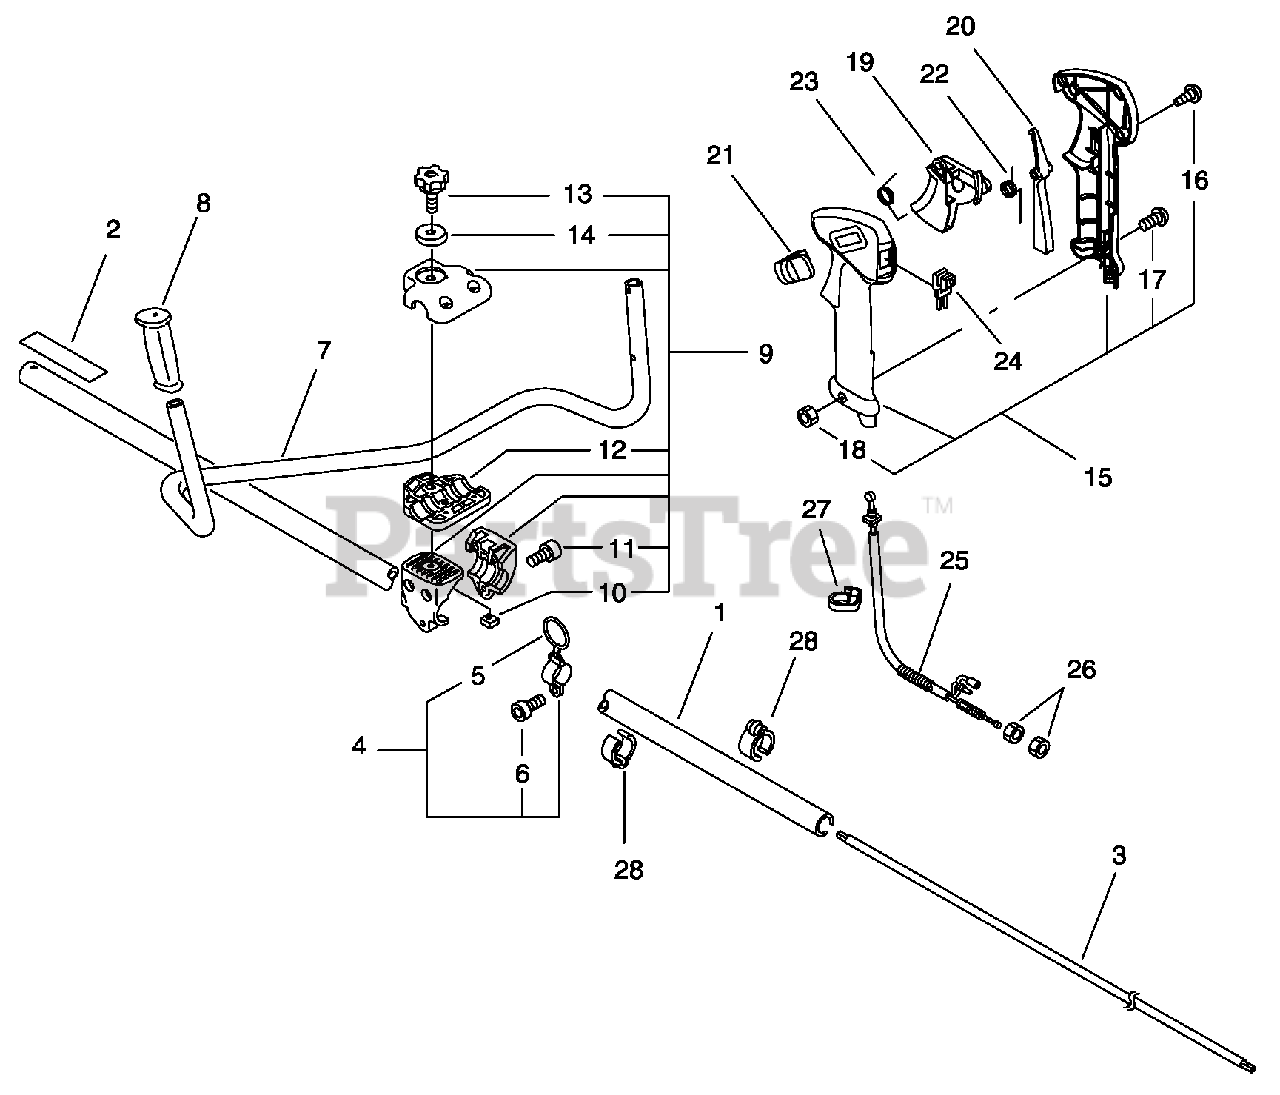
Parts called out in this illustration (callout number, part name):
1	MAIN PIPE ASSY
2	LABEL - CAUTION
3	DRIVESHAFT
4	HANGER KIT
6	SCREW - 5X12
7	HANDLE - FRONT
8	GRIP, HANDLE
9	HANDLE BRACKET KIT
11	SCREW - 5X30
12	BRACKET, HANDLE - LOWER
13	THUMBSCREW
14	WASHER - 8
15	CONTROL HANDLE ASSY
16	SCREW - 4X16
17	SCREW - 5X30
19	TRIGGER, THROTTLE
20	LEVER, TRIGGER LOCKOUT
21	LOCK, THROTTLE
22	SPRING, TRIGGER
23	SPRING, LOCKOUT LEVER
24	SWITCH, IGNITION
25	CABLE, THROTTLE
